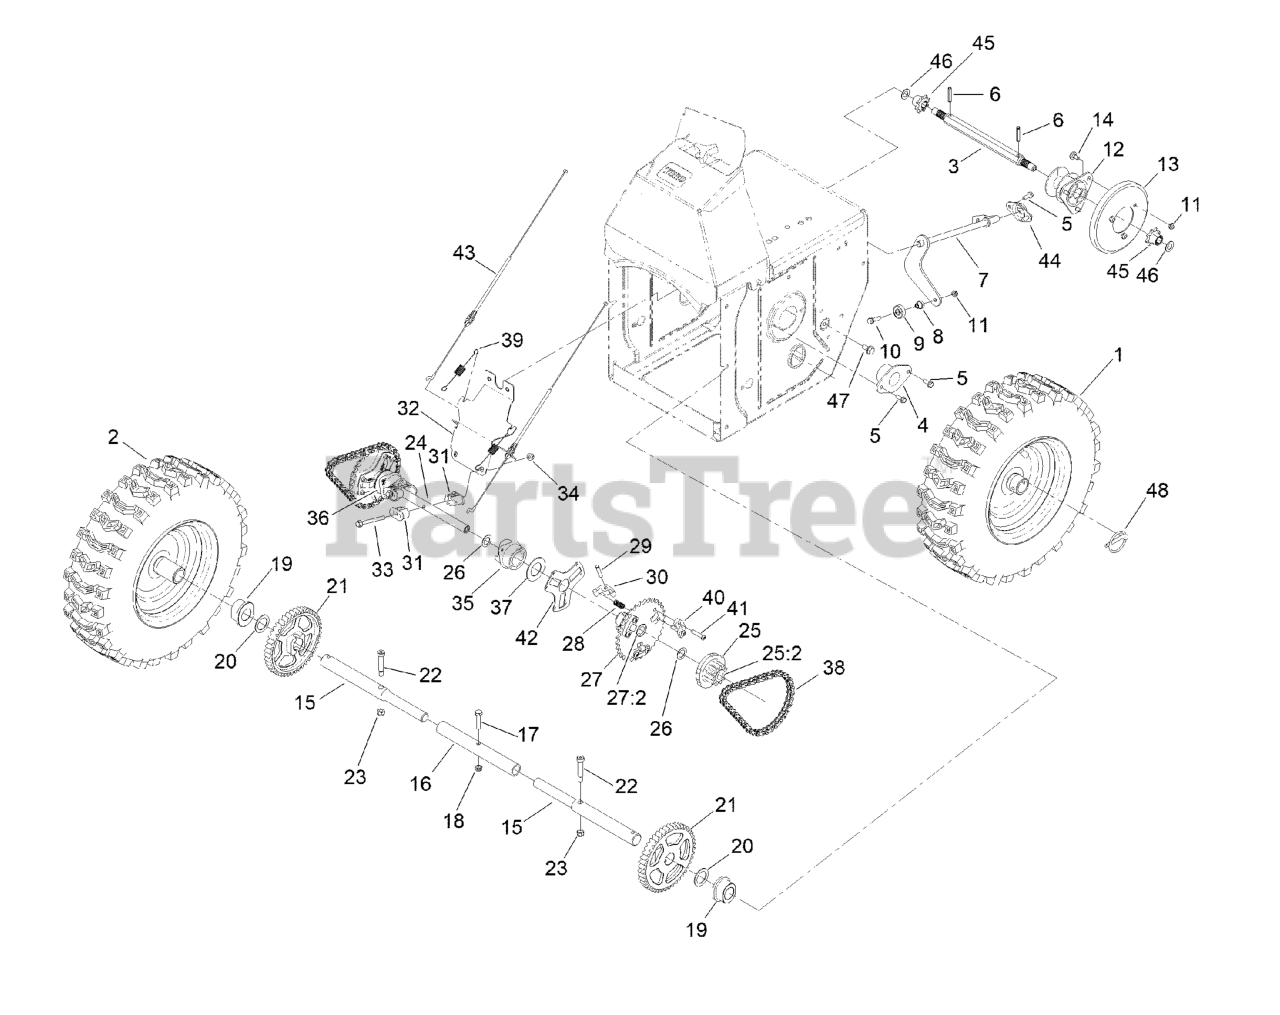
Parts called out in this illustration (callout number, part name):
1	LH WHEEL AND TIRE ASM
2	RH WHEEL AND TIRE ASM
3	SHAFT-HEX
4	RETAINER-BEARING
5	SCREW-HWH
6	PIN-ROLL, SLOTTED
7	SHIFT ROD
8	SPACER-PLATE, SHIFT
9	BEARING-BALL
10	SCREW-HWHTF
11	NUT-HEX
12	TRUNNION
13	WHEEL-FRICTION
14	SCREW-SHOULDER
16	TUBE-AXLE
17	SCREW-HH
18	NUT-HEX
19	BUSHING-AXLE
20	WASHER-THRUST
21	GEAR-AXLE
22	BOLT-SHOULDER, HSH
23	NUT-HEX
24	SHAFT-INTERMEDIATE
25	11T GEAR ASM
25:2	BUSHING-FLANGE
26	WASHER-FLAT
27	32T SPROCKET ASM
27:2	BUSHING-FLANGE
28	SPRING-COMPRESSION
29	PIN-DOWEL
30	PAWL-CLUTCH
31	GUIDE-COLLAR
32	BRACE-SHIFT, COLLAR
33	SCREW-HHF
34	SCREW-SHOULDER
35	COLLAR-SHIFT, LH
36	COLLAR-SHIFT, RH
37	WASHER-THRUST
38	CHAIN-ROLLER
39	SPRING-EXTENSION
40	SUPPORT-PAWL
41	SCREW-BHCS
42	RETAINER-PAWL, PIN
43	CABLE-CLUTCH
44	RETAINER-ROD, SHIFT
45	GEAR-PINION, 8 TOOTH
46	WASHER-PLAIN
47	SCREW-HWHTF
48	PIN-KLIK
